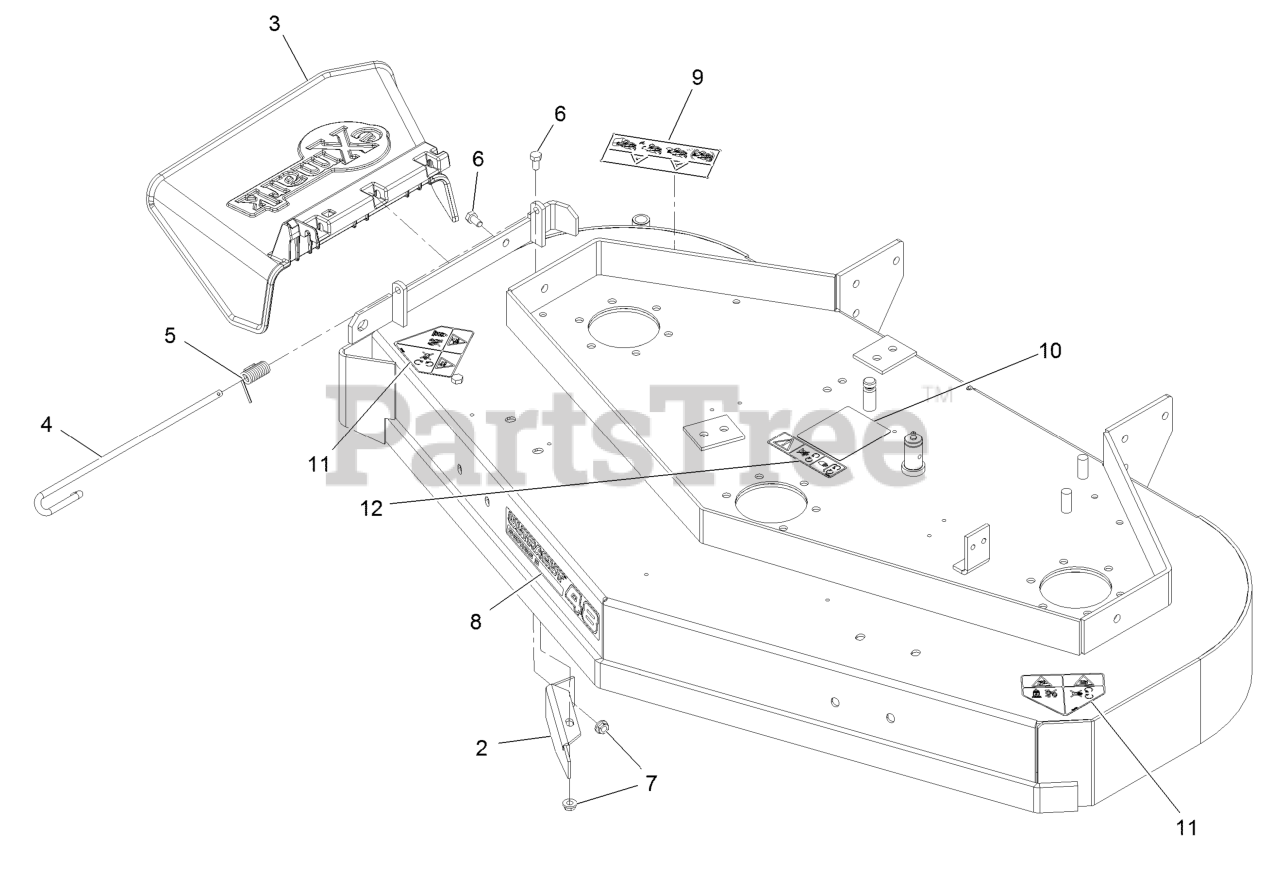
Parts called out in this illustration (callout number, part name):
2	Baffle-Dogleg
3	Deflector-Discharge
4	Pin-Chute
5	Spring, Torsion
6	Screw-HH 5/16-18 X 5/8
7	Nut-Whizlock 5/16-18
8	Decal-Ultracut 48 Series 3
9	Decal-Warning, Bagger
10	Decal-Routing, Belt
11	Decal-Danger
12	Decal-Cover, Missing
